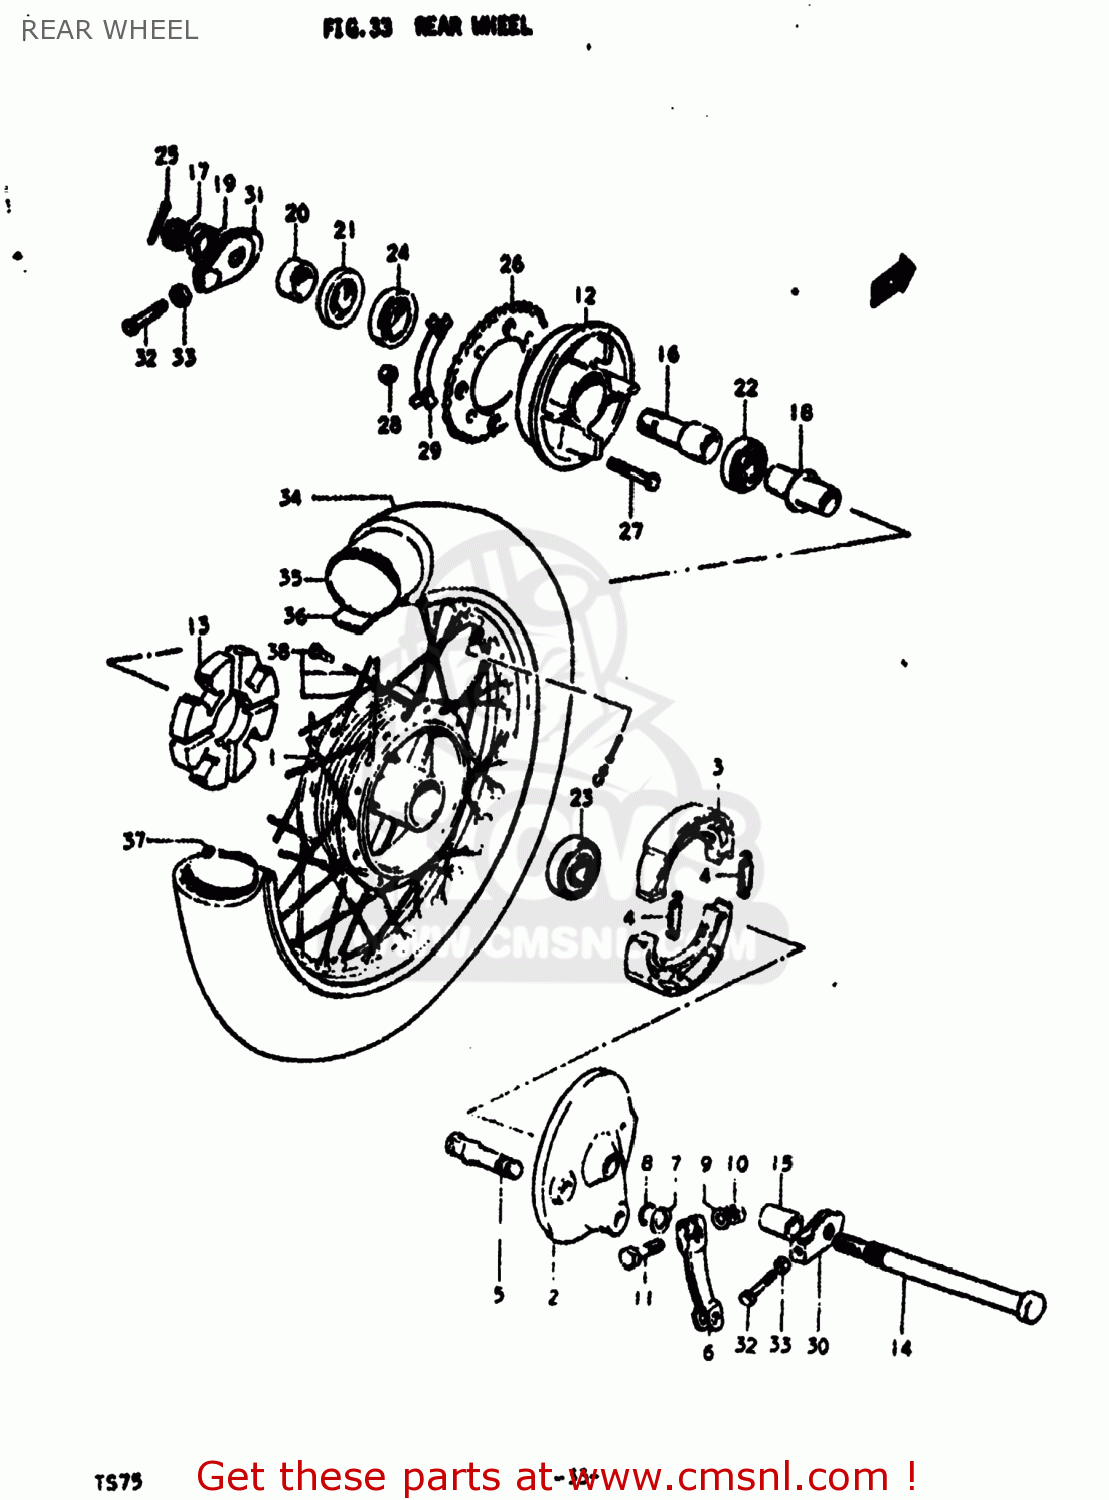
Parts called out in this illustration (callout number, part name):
1	HUB,REAR
2	PANEL,REAR HUB
3	SHOE,BRAKE
4	SPRING(L:34)
5	CAM,FR BRAKE
6	LEVER,REAR BRAKE CAM
7	WASHER(12.5X20X1)
8	O RING(D:2.5,ID:11.4)
9	WASHER
10	NUT
11	BOLT
12	DRUM,REAR SPROCKET MOUNT
13	CUSHION,REAR DRUM
14	AXLE,REAR
15	SPACER(12.2X22X30.5)
16	SHAFT,RR SPROCKET DRUM
17	NUT
18	SPACER,REAR HUB BEARING
19	NUT
20	SPACER(17X25X10.5)
21	SEAL OIL(25X40X6)
22	BEARING, LH
23	BEARING, RH
24	BEARING
25	COTTER PIN
26	SPROCKET,REAR
27	BOLT(8X33.5)
28	NUT
29	WASHER
30	ADJUSTER,CHAIN,R
31	ADJUSTER,CHAIN,L
32	BOLT(6X38)
33	NUT
34	TIRE
35	TUBE,INNER
36	PROTECTOR,INNER TUBE
37	RIM,REAR WHEEL
38	SPOKE SET,REAR
